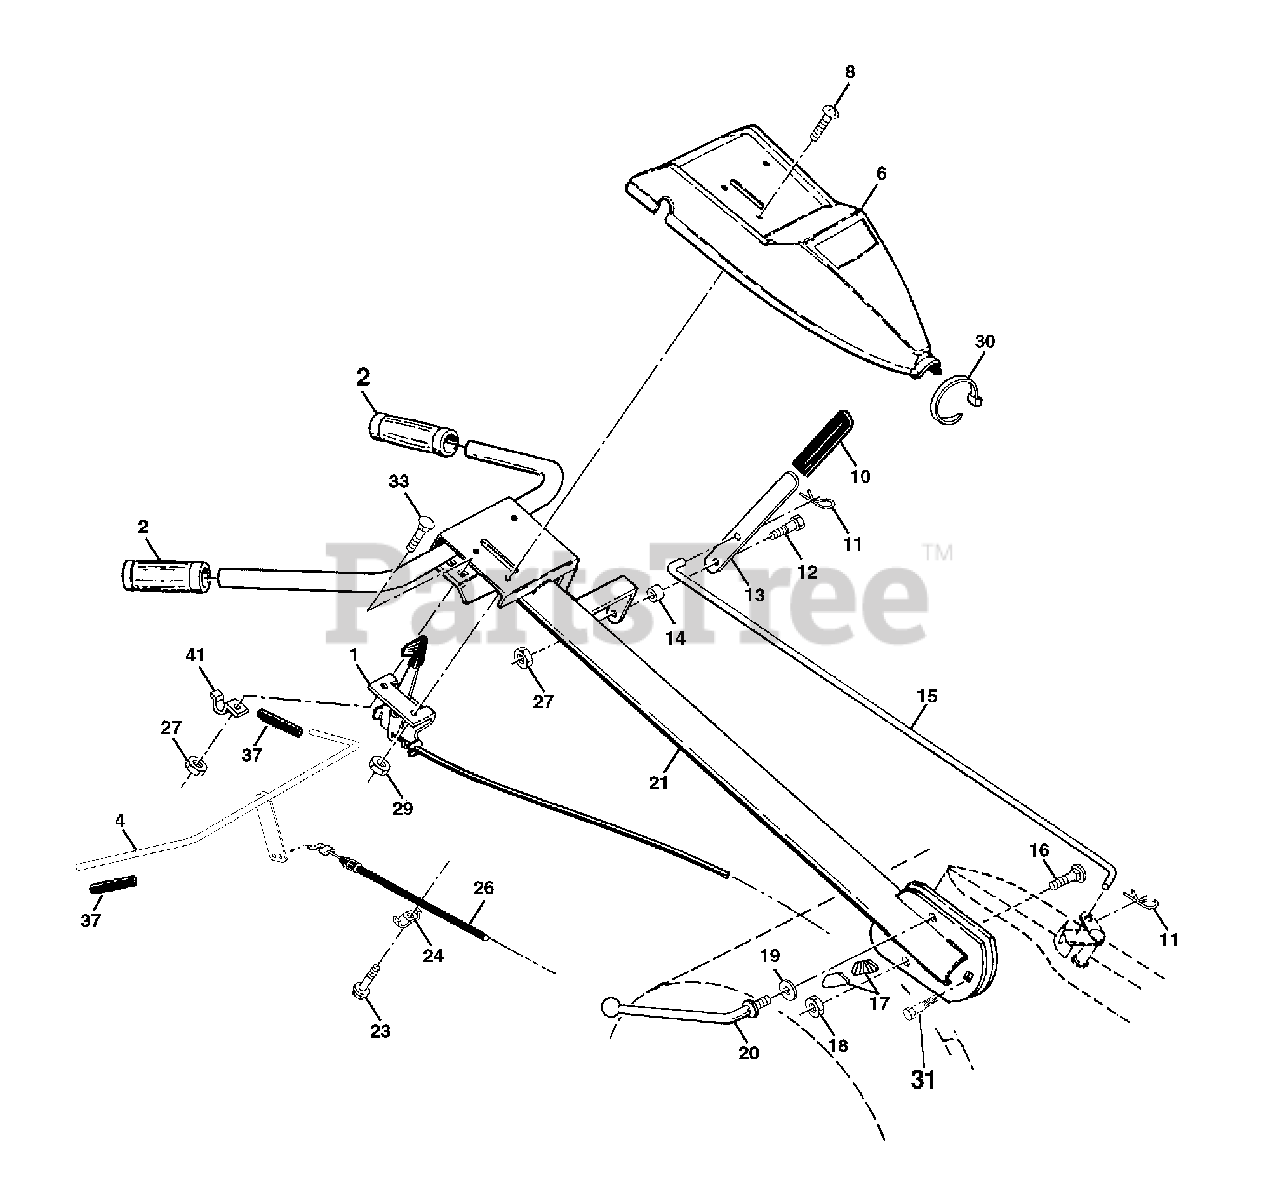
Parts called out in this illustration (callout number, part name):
1	Control, Throttle
2	Grip, Handle
4	Bar Assembly, Control
6	Panel, Control
8	Screw, Truss Hd. #10-24 UNC x 1/2
10	Grip, Handle
11	Clip, Hairpin
12	Bolt, Shoulder
13	Handle, Shift
14	Grommet, Rubber
15	Rod, Shift
16	Bolt, Carriage 3/8-16 x 1 Gr. 5
17	Lock, Handle
18	Nut, Crownlock 3/8-16 Unc
19	Washer 13/32 x 1 x 11 Ga.
20	Lever, Lock, Handle
21	Handle
23	Screw, Hex Washer Hd. Slotted #10-24 x 1/2
26	Cable, Clutch
27	Nut Hex Flange 1/4-20 Unc
29	Nut, Keps #10-24 UNC
30	Tie, Cable
31	Bolt, Pivot
33	Bolt, Carriage 1/4-20 UNC x 1/2
37	Grip, Bar, Control
41	Clamp, Bar, Control
